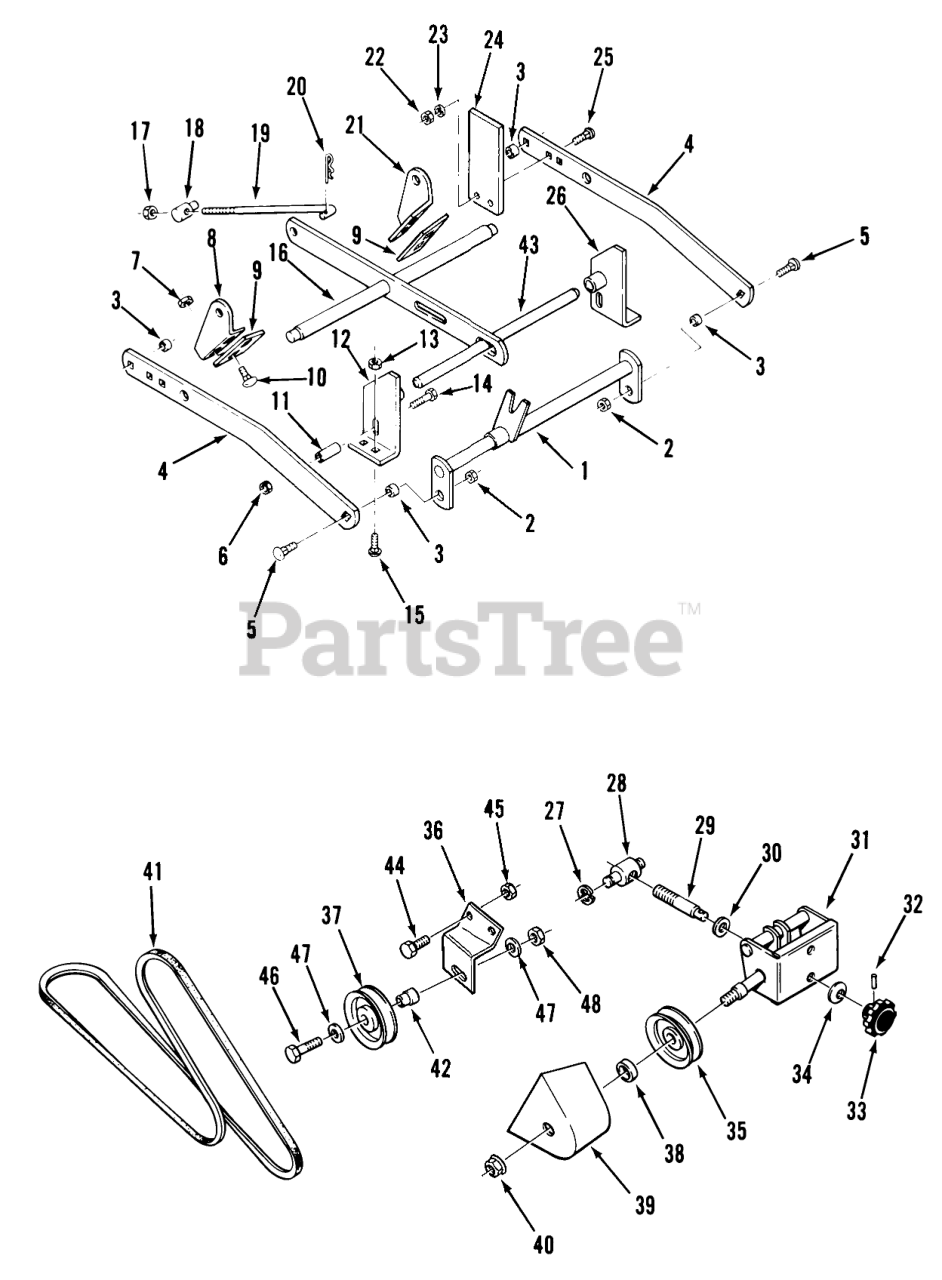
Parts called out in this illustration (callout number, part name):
1	Hitch
2	LOCKNUT-FLANGE
3	SPACER
4	Bar Draft
5	Bolt
6	Nut
7	Nut
8	Bracket-R.H.
9	PLATE
10	Bolt
11	SPACER-BEARING
12	Bracket-R.H.
13	Nut
14	CARRIAGE BOLT -4
15	Bolt-Carriage
16	Leveler Assembly
17	NUT
18	TRUNNION-LIFT
19	ROD-LEVELER
20	Hairpin
21	Bracket-L.H.
22	Nut
23	Collar
24	BUMPER
25	Bolt-Carriage
26	Bracket-L.H.
27	RING-RETAINING
28	TRUNNION-DOUBLE
29	ROD ADJ
30	Washer
31	ASSY FRONT SUPPORT
32	PIN-ROLL
33	KNOB-ADJUSTMENT
34	WASHER-SPRING
35	Pulley-V
36	BRACKET FLAT IDLER
37	PULLEY-FLAT IDLER
38	SPACER
39	Belt Cover
40	Nut 3/4-16 MF
41	V-BELT
42	SPACER
43	Front Shaft
44	BOLT
45	Nut
46	Bolt
47	Washer
48	NUT
